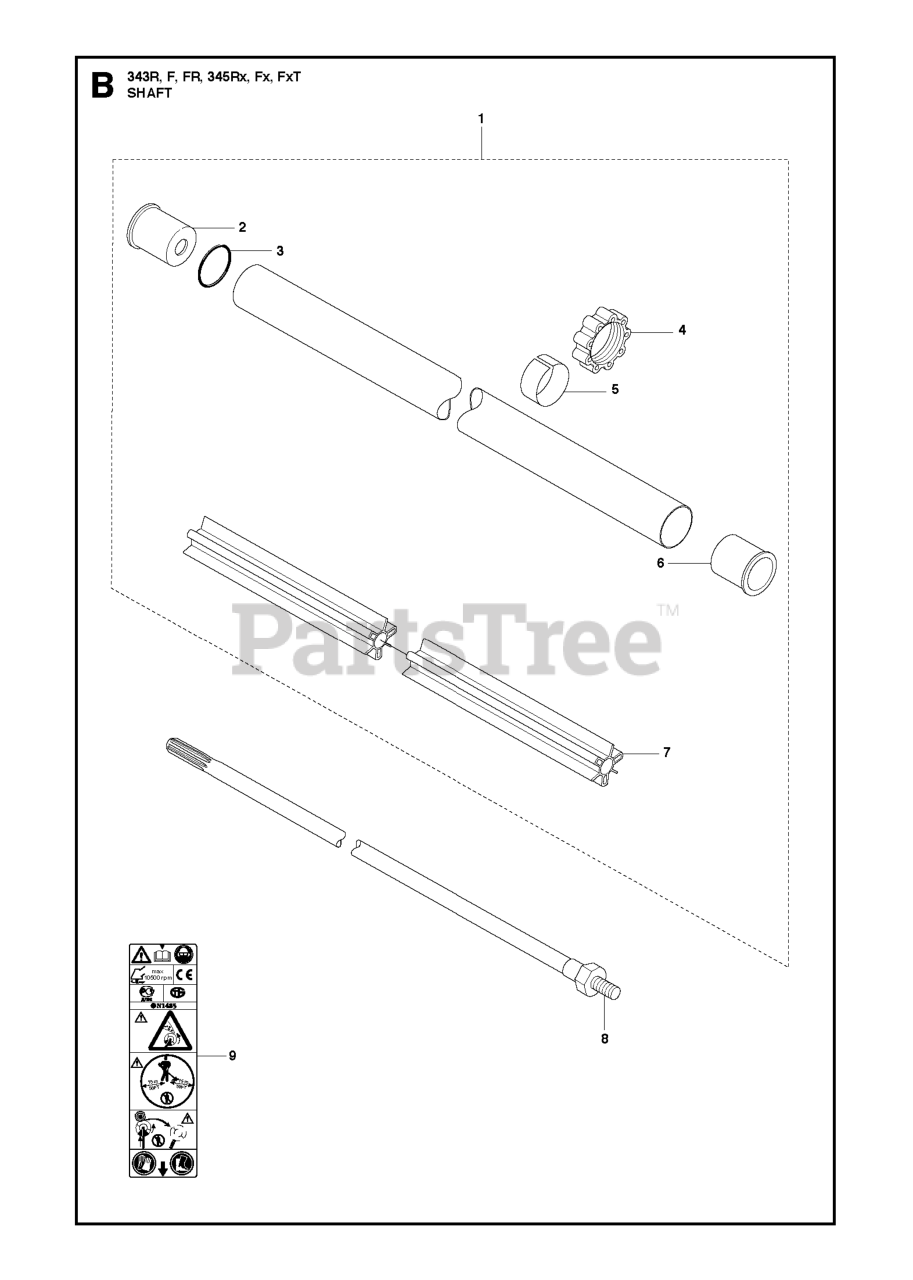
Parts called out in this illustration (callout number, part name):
1	RP TUBE ASSY
2	SPACER SLEEVE
4	MOVEMENT LIMITER
5	%BAND
6	SPACER SLEEVE
7	BEARING SHAFT
8	SHAFT
9	LABEL WARNING TRIMMERS AND BRU
